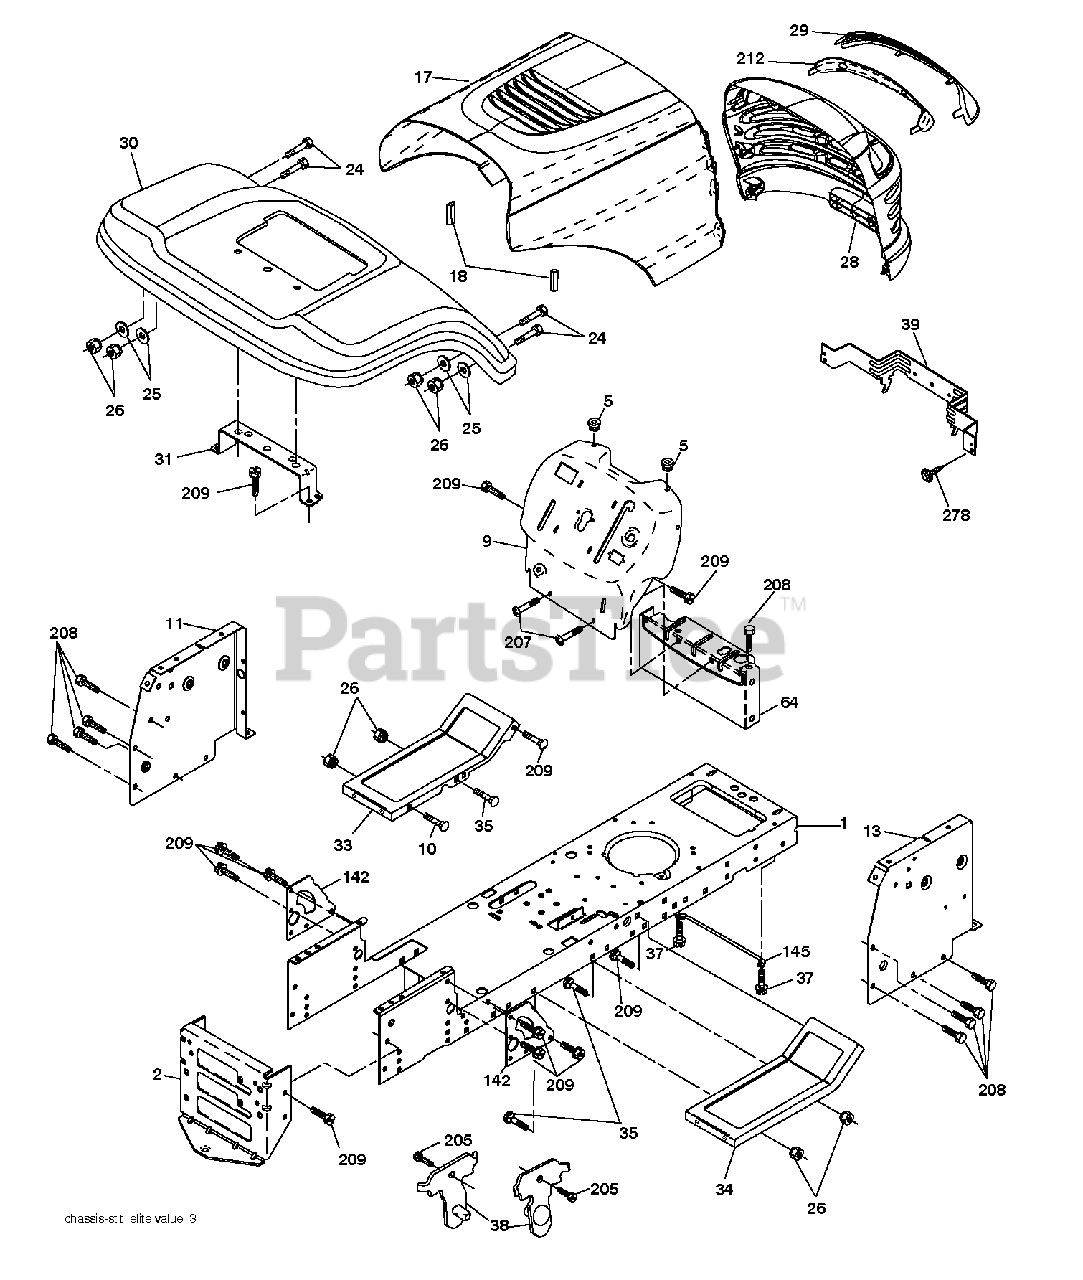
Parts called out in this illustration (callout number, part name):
1	CHASSIS STAMPING
2	DRAWBAR, 12GA
5	BUMPER.RUBBER.HOOD
10	BOLT D
11	PANEL.DASH.LH.LTX
18	BUMPER.HOOD.LARGE.1.75"
25	WASHER
26	NUT
31	BRACKET FENDER
38	BRACKET.ASM.PIVOT.MOWER.REAR
39	BRACKET PIVOT
64	DASH LOWER
142	PLATE REINFORCEMENT
145	ROD.PIVOT.HOOD
207	SCREW, 5/16-18 X 1/2
208	SCREW 3/8-16X1/2
209	SCREW, 3/8-16X3/4
278	SCREW.#10 X 0.750.BOS THREAD
